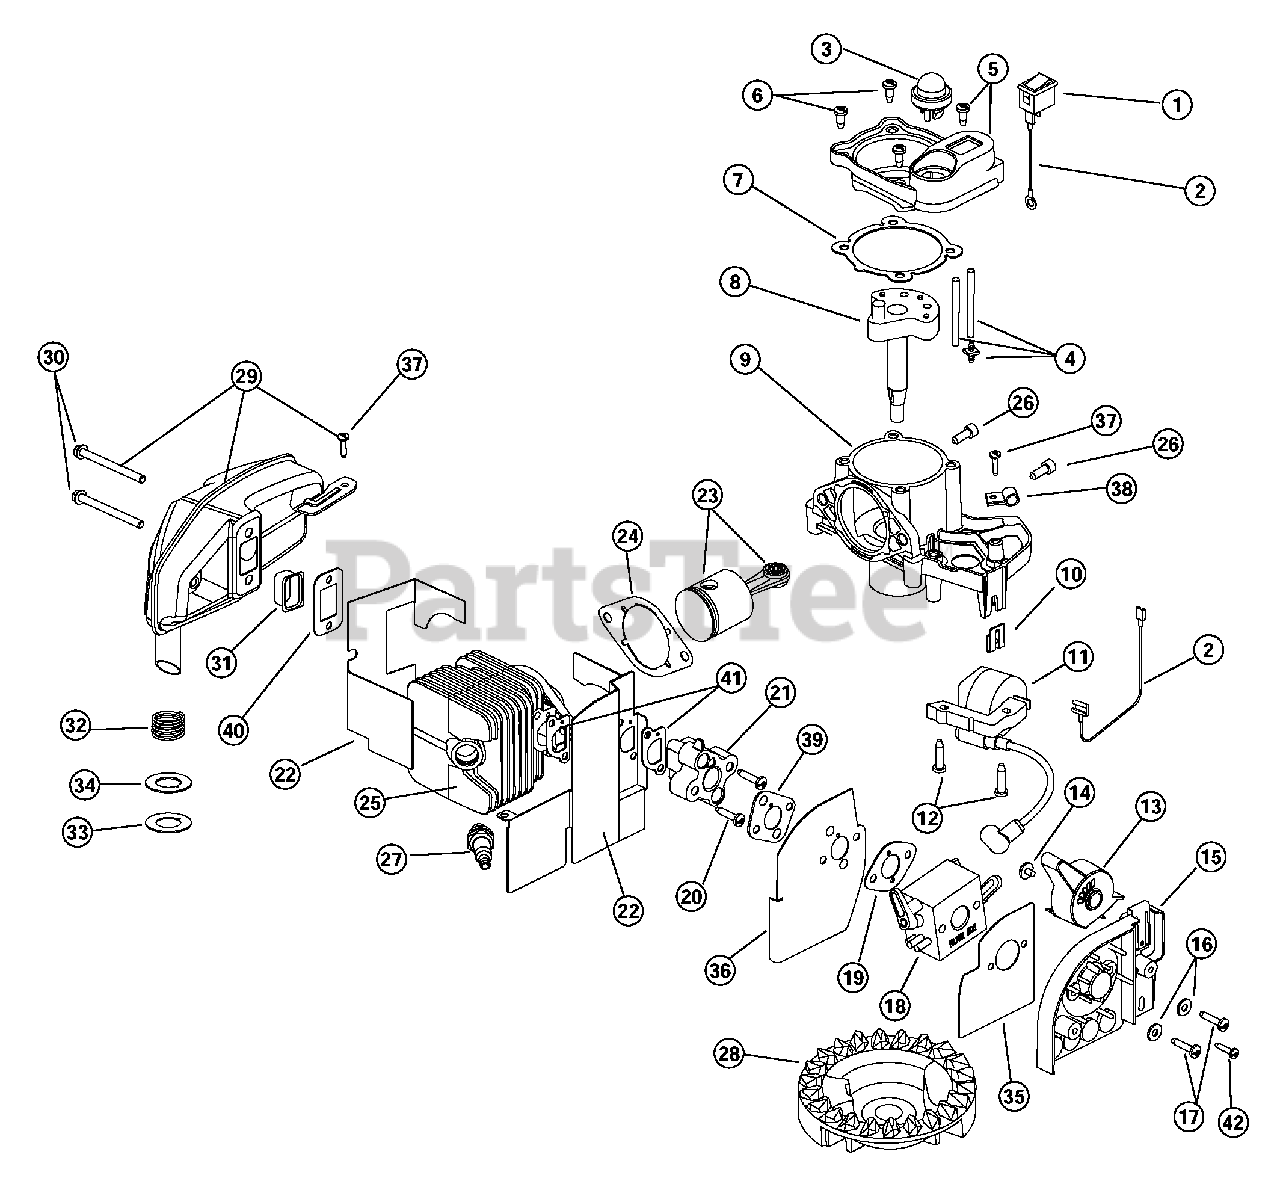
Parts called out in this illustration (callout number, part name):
1	On/Off Stop Control Switch with Wire
2	Switch and Coil Replacement Wires
3	Primer Bulb
4	Return Lines
5	Crankcase Plug
6	Crankcase Plug Screws
7	Crankcase Plug Gasket
8	Power Shaft Assembly
9	Crankcase Assembly
10	Tinnerman Nut
11	Module Assembly
12	Module Screw
13	Throttle Lever
15	Air Cleaner Base
17	Carburetor Mount Screw
18	Carburetor
19	Carburetor Gasket
20	Spacer Mounting Screw
21	Carburetor Spacer
22	Cylinder Baffle Assembly
23	Piston and Rod Assembly
24	Cylinder Gasket
25	Cylinder Assembly
26	Cylinder Bolt
27	Spark Plug
28	Flywheel
29	Muffler Assembly
30	Muffler Mounting Screw
31	Spark Arrestor Screen
32	Exhaust Tube Spring
33	Exhaust Tube Washer
34	Exhaust Tube Gasket
35	Air Filter Heat Shield
36	Carburetor Heat Shield
39	Heat Shield Gasket
40	Exhaust Gasket
41	Intake Gasket
